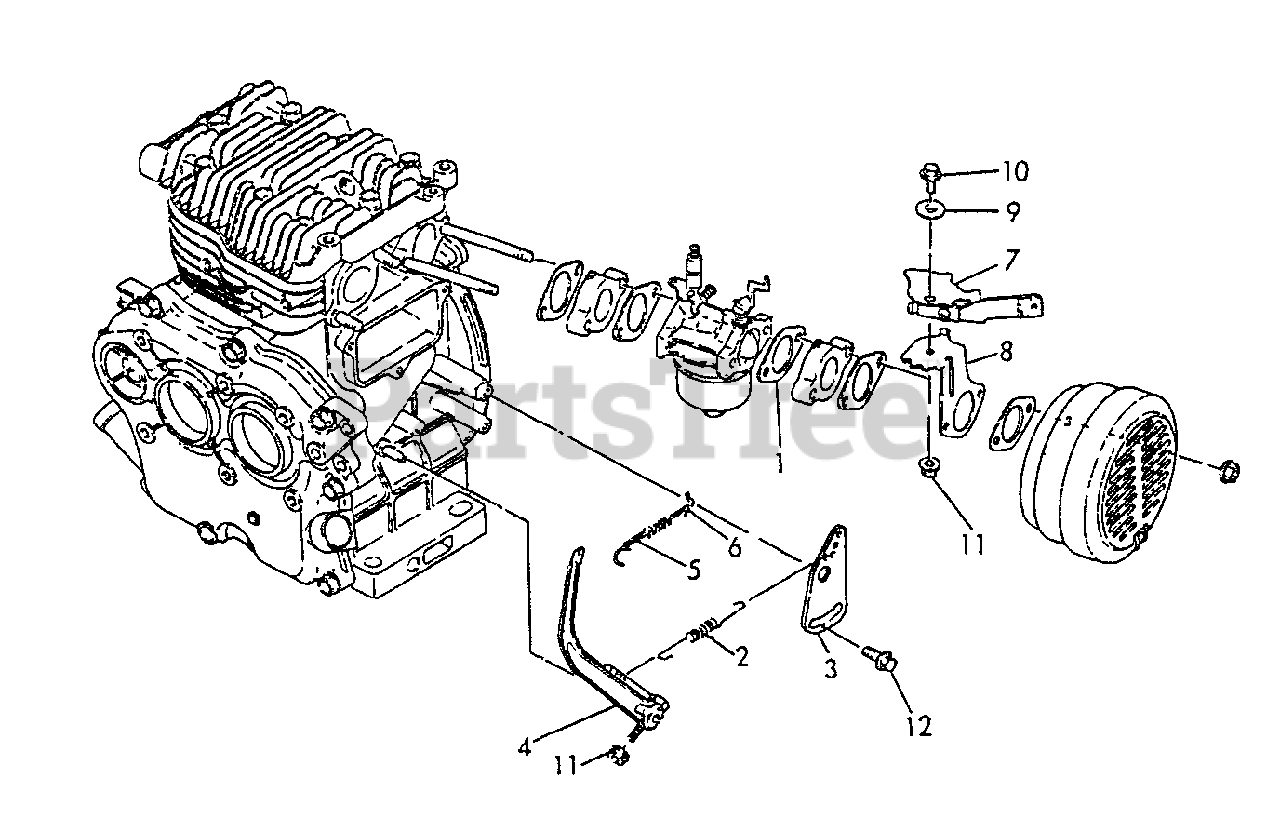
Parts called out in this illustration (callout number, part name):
2	SPRING, REGULATOR
3	HANDLE, REGULATOR
4	LEVER, GOVERNOR
5	LINK, THROTTLE
6	SPRING, TENSION
7	LEVEL ASSY
8	BRACKET, LEVER
9	COLLAR
10	BOLT - 6×12 -- PLATED
11	U-NUT M6
12	BOLT - 6×8 -- PLATED
